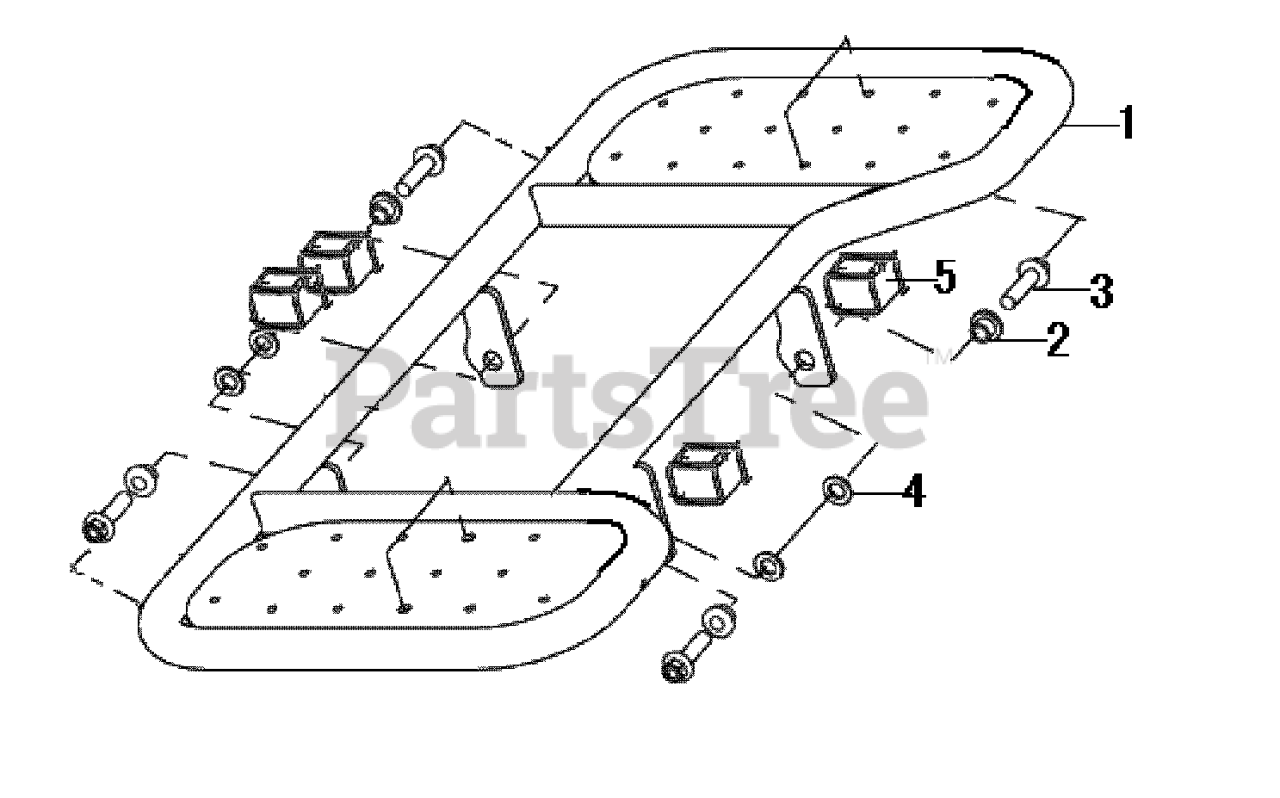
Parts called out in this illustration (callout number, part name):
1	FOOTREST ASSY.
2	RUBBER BUSHING
5	RUBBER PAD
